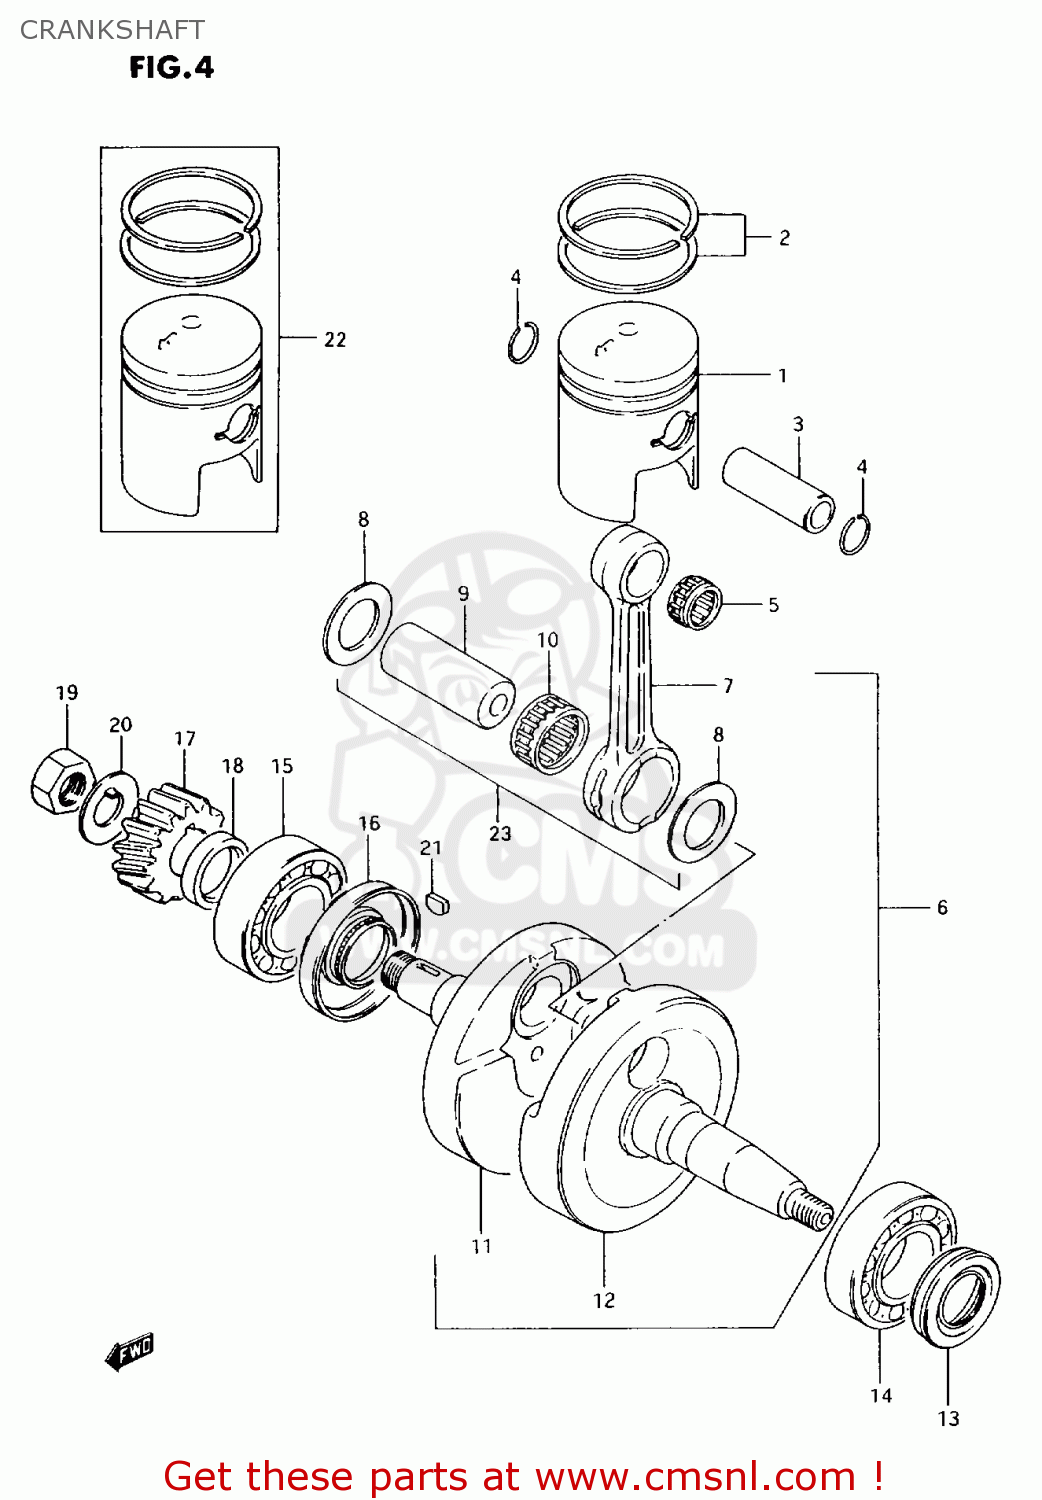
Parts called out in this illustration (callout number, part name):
1	PISTON (50.00MM)
2	RING SET,PISTON
3	PIN,PISTON 14MM
4	RING,SNAP 14MM
5	BEARING 14X18X19.8
6	CRANKSHAFT ASSY
7	ROD,CONNECTING
8	WASHER (20X34X1)
9	PIN, CRANK
10	BEARING(20X26X16.7)
11	CRANKSHAFT, RH
12	CRANKSHAFT,L
13	SEAL,OIL(19.6X37X8)
14	BEARING(25X52X15)
15	BEARING(20X52X15)
16	SEAL,OIL(26X52X8)
17	GEAR,PRIMARY DRIVE(NT:16)
18	SPACER(20X28X7)
19	NUT
20	WASHER
21	KEY
22	PISTON SET(OS:0.5)
23	CON ROD SET (INCLUDING REF.NO. 5, 7, 8,
